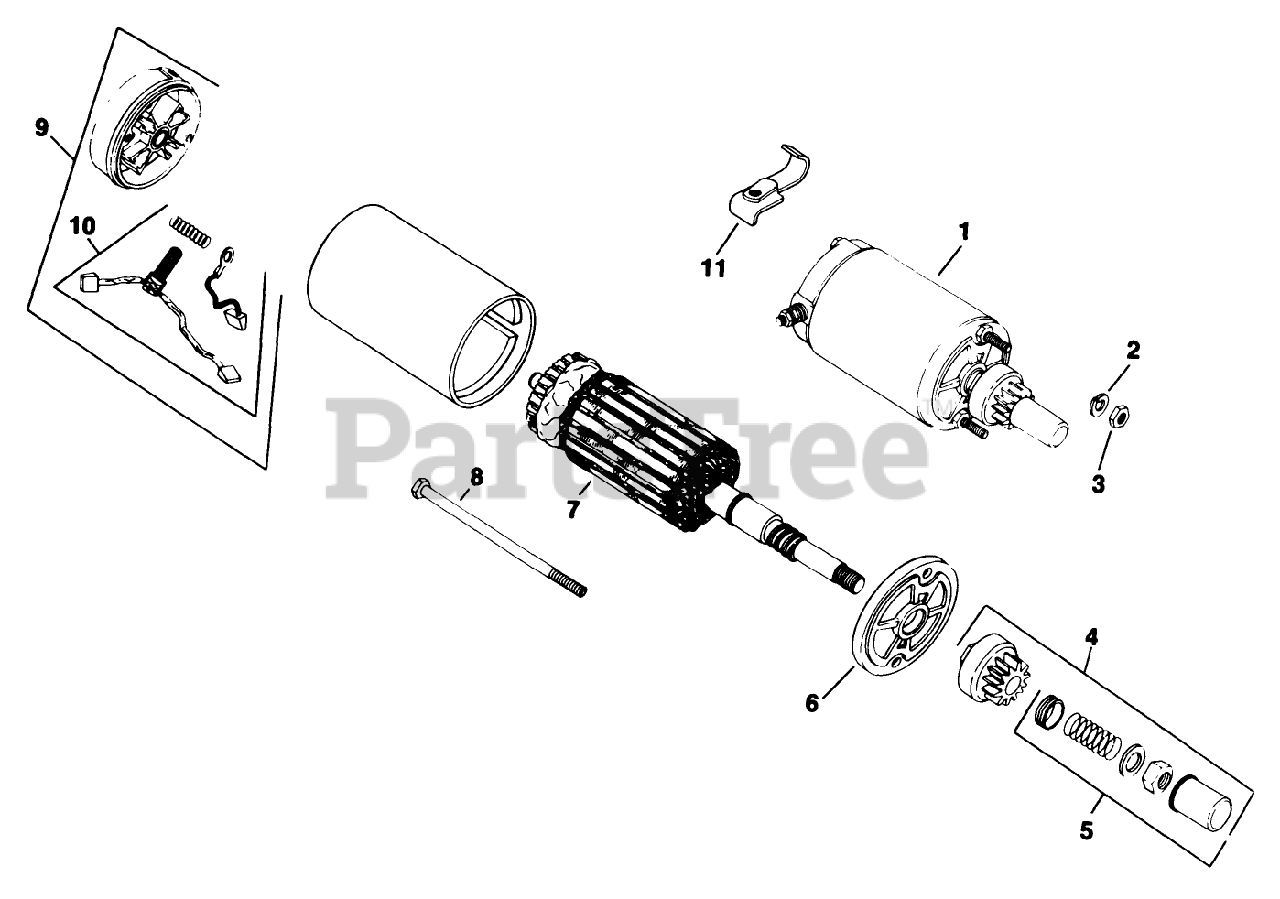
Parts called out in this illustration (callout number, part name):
1	Starter Assy. (Incl. Ref. #4-10)
2	Washer
4	Kit-Drive (Incl. Ref. #5)
5	Kit-Drive Parts
6	Cap-Drive End
7	Armature
9	Cap-Commutator End (Incl. Ref. #10)
10	Kit-Brush
11	Bracket-Mounting
